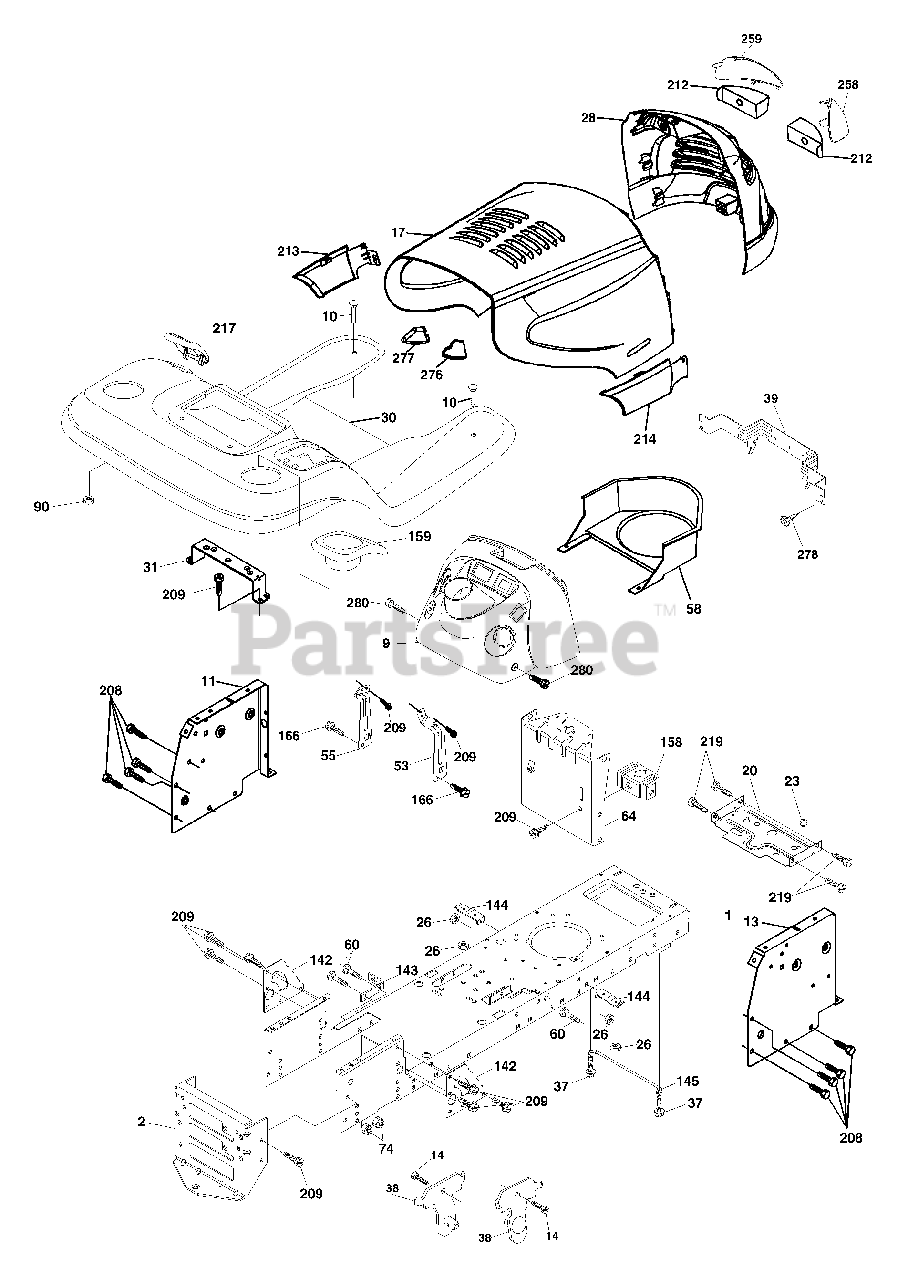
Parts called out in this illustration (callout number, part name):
1	Chassis Stamping
9	Dash P/L M
10	Bolt Carriage 3/8-16 x 1
11	Panel Dash Lh
13	Panel Dash Rh
14	Screw Thdrol 3/8-16 x 1/2
17	Hood
20	Plate Mtg Battery Fuel Tank Fr
26	Nut Lock Hex W/Ins 3/8-16 unc
28	Grille/Lens Asm.
30	Fender Footrest STLT Pnt
31	Bracket Support Fender
37	Screw Thdrol 5/16-18 x 1/2 TYT
38	Bracket Asm Pivot Mower Rear
39	Bracket Pivot
53	Bracket Dash RH
55	Bracket Dash LH
58	Air Duct Engine
60	Bolt Rdhd Sqnk 3/8-16 unc x 3/4
64	Dash Lower STLT
74	Nut Crownlock 3/8-16 unc
90	Nut Self-thd Wsh-Hd 1/4
142	Plate Reinforcement STLT
143	Bracket Swaybar Chassis
144	Bracket Pnt Footrest STLT
145	Rod Pivot Chassis/Hood
158	Bracket Parking Brake
159	Cupholder
166	Screw HWHD Hi-Lo #13-16 x 3/4
208	Screw Thdrol 3/8-16 x 1/2 TYT Bl
209	Screw 3/8-16 x 3/4
212	Insert Lens Reflect
213	Skirt Side LH
214	Skirt Side RH
217	Console Fuel Window
219	Screw 5/16-18 x 3/4
258	Lens RH
259	Lens LH
276	Bumper Hood RH
277	Bumper Hood LH
278	Screw Quadx WSHD #10-14 x 1
280	Screw 3/18-16 x 1
